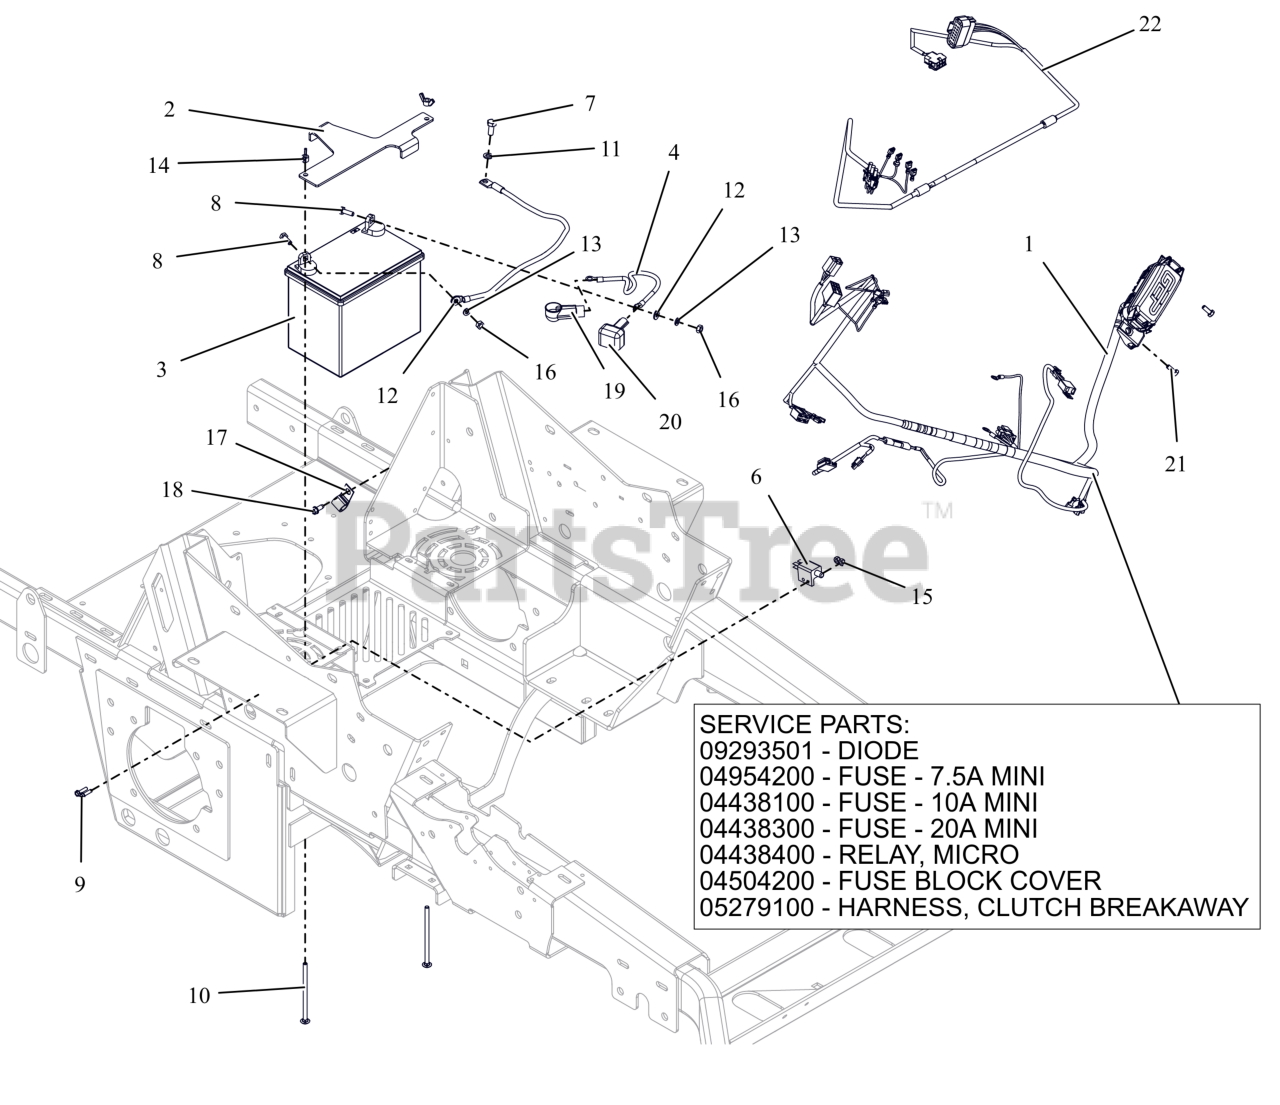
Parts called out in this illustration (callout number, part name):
1	HARNESS- WIRE PT300 MAIN
1	DIODE, CONNECTOR SHELL
1	FUSE, 7.5 AMP MINI-ATC
1	FUSE,10 AMP MINI-ATC
1	FUSE,20 AMP MINI ATC
1	RELAY,MICRO5 TERML W/RESISTOR
1	COVER, HARNESS FUSE/RELAY MOD
1	HARNESS, CLUTCH BREAKAWAY
2	HOLDDOWN- BATTERY
3	BATTERY, 300 CCA 10U1L
4	CABLE, STARTER 13.00"
6	SWITCH- DOUBLE POLE N.O./N.O.
7	BLT, HEX M8-1.25X20 G8.8 ZCC
8	BLT, HEX .25-20X.75 G5 ZCC
9	BLT, HWH #10-24X.75 ZCC
10	BLT, RHSN .25-20X4.50 G5 ZCC
11	WSHR,LK-REG .312X.078 ZCC
12	WSHR,FLT .281X.625X.065 ZCC
13	WSHR,LK-REG .250X.062 ZCC
14	NUT, LK-WING .25-20 ZCC
15	NUT-LK-NYL #10-24 G2 ZCC
16	NUT-STD .250-20 G2 ZCC
18	SCR,TAP .25-20X.625 HWH ZCC
19	BOOT, .65ID POS
20	INSULATOR
21	BLT, HEX M6-1X16 G8.8 ZCC
22	HARNESS- EFI ENG ADAPTER PT300
